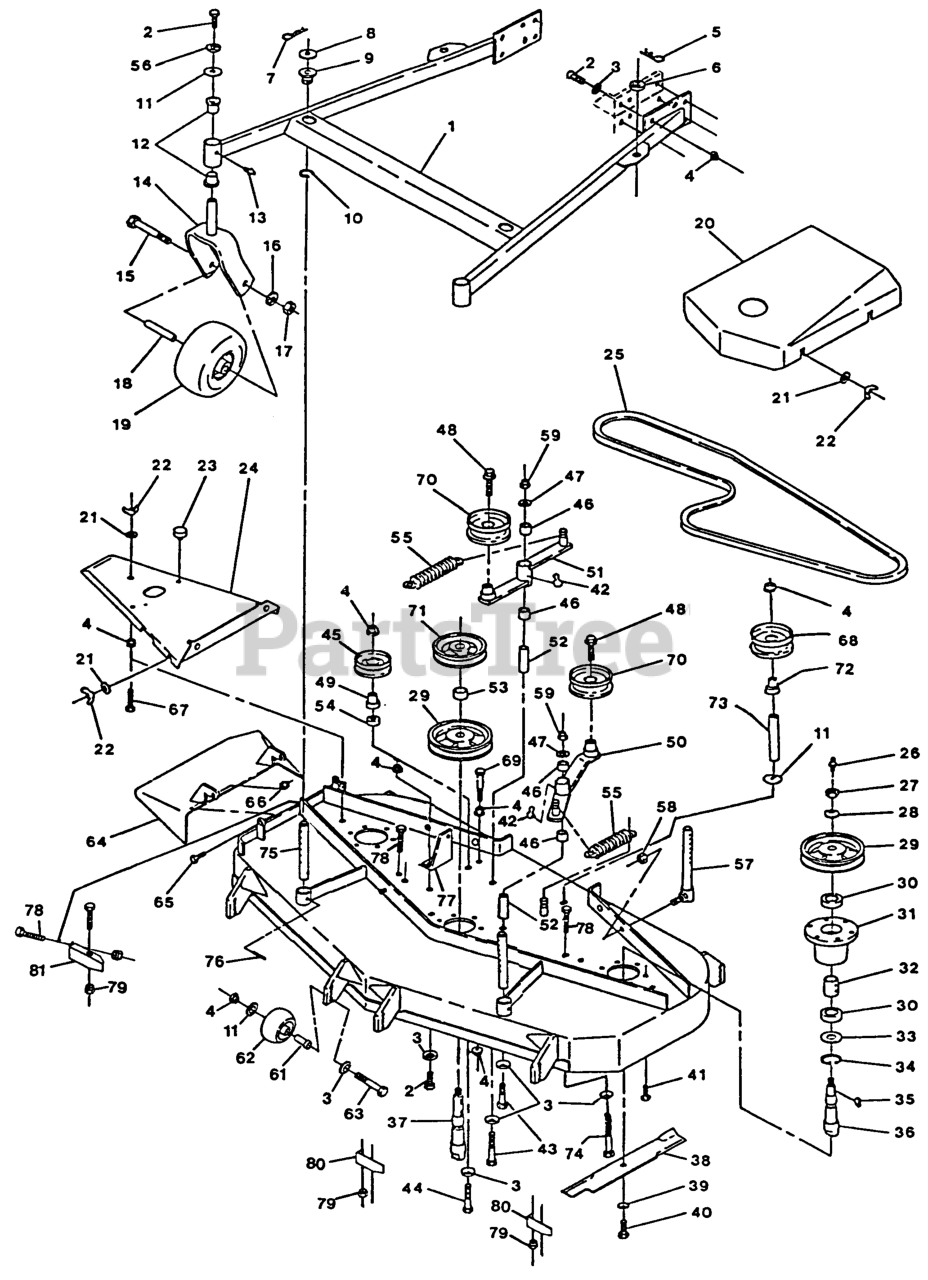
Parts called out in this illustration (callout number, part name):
5	PIN,HAIR COTTER
8	WASHER-FLAT
9	BUSHING-DECK
12	BEARING-FLANGED
22	NUT-WING
24	WLD,DECK COVER
25	BELT-DRIVE, BLADE
28	WASHER-SPRING
29	SHEAVE,BLADE DRIVE
32	SPACER,BEARING
33	SEAL,MECHANICAL DUST
34	RING,SNAP WLDS N5000-244
36	SPINDLE-OUTER BLADE
37	SPINDLE-CENTER BLADE
39	WASHER-SPRING
41	SCRW,TPTTE HH
43	SCREW-HH
46	SLEEVE-BEARING
49	BUSHING-IDLER
50	Arm Weldment Deck Drive Idler
51	Arm Weldment - Deck Idler
52	BUSHING-PIVOT, IDLER
53	SPACER-TUBE
55	SPRING-EXTENSION
61	BUSHING-ROLLER
62	ROLLER-SCALP, ANTI
68	PULLEY-IDLER
70	IDLER,PULLEY
72	BUSHING,IDLER
73	SPACER-FENDER
75	ROD,DECK SUPPORT
77	BRACKET,SPRING ANCHOR
81	WLD,BAFFLE DISCHARGE
